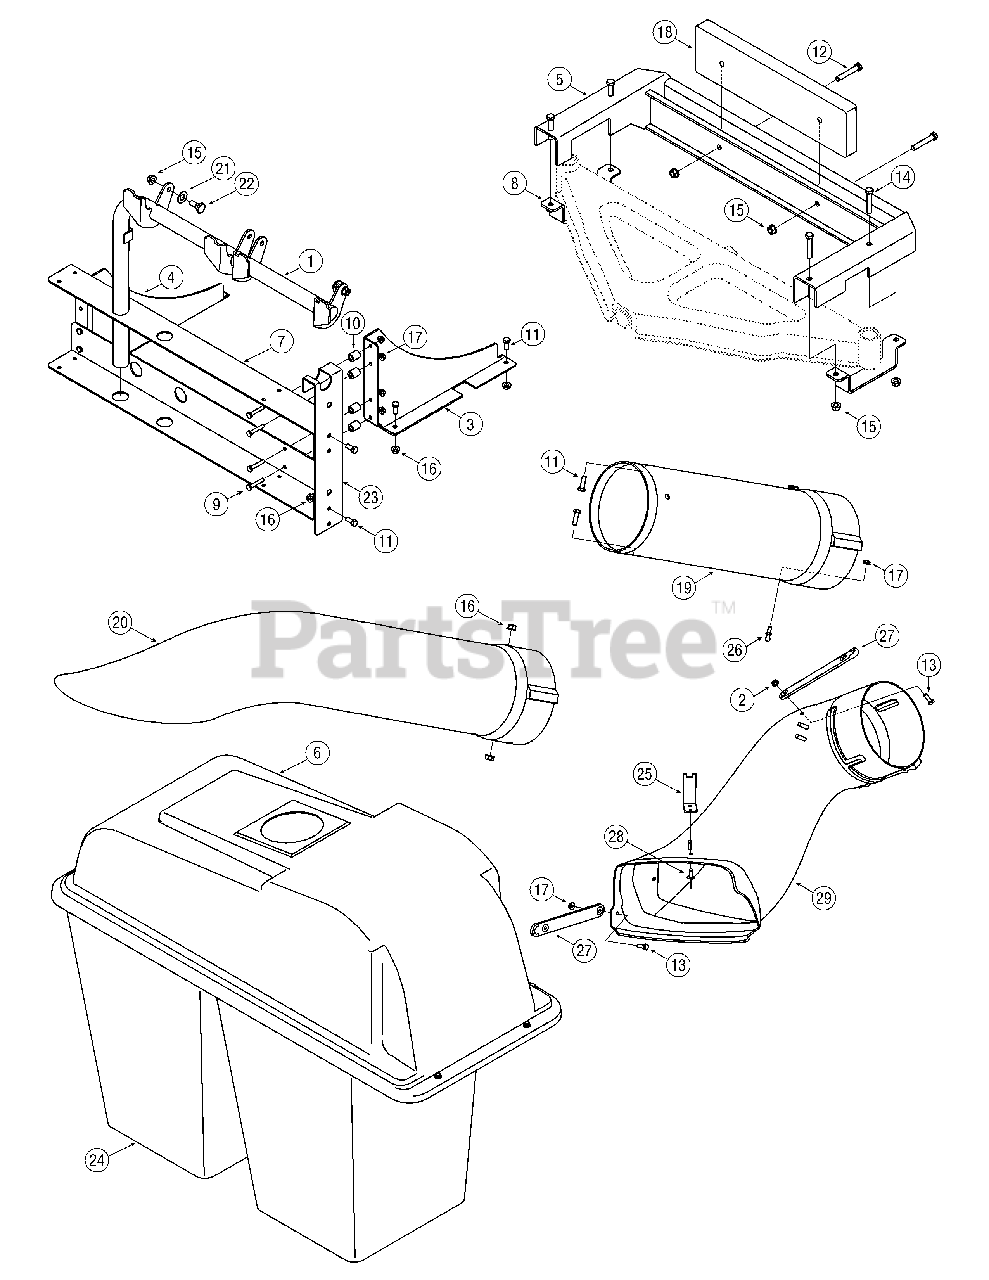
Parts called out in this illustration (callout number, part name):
2	Flange Lock Nut 1/4-20
6	Grasscatcher Cover Assembly
9	Hex Bolt 1/4-20 x 1.50
10	Spacer .325 x .625 x .770 LG
11	Hex Bolt 5/16-18 x 1.00
12	Hex Bolt 3/8-16 x 2.25
13	Hex Bolt 1/4-20 x 1.25
14	Hex Bolt 3/8-16 x 2.0
15	Top Lock Flange Nut 3/8-16
16	Flange Lock Nut 5/16-18
17	Flange Lock Nut 1/4-20
18	Weight Bar
19	Chute Extension
20	Chute Tube
21	Bell Washer
22	Shoulder Screw
24	Grass Bag Assembly
26	Grasscatcher Pin
27	Chute Strap
28	Rivet .187 Dia. #66
29	Chute Elbow
